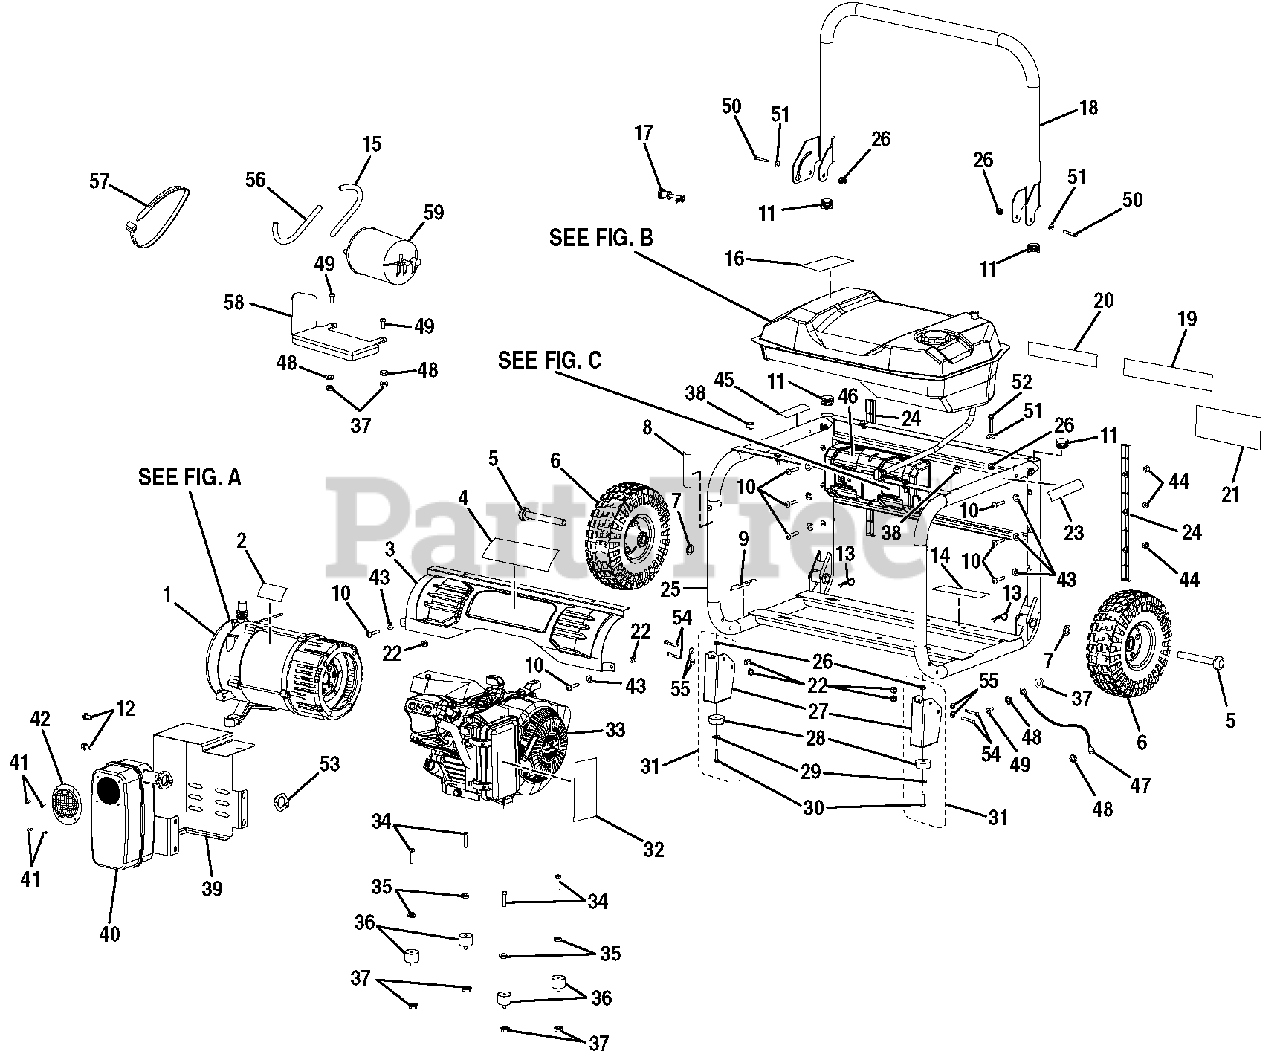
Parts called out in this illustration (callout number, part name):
1	Generator Head Assembly (See Figure A)
2	Data Label
3	Back Panel Assembly
4	Back Panel Logo Label
7	Washer (5/8 in.)
8	Hot Surface Label
9	Label (UL fire warning)
10	Bolt (1/4-20 x 42.5 mm, Torx Hd.)
12	Bolt (5/16-24 x 5/8 in.)
13	Hitch Pin
14	Lubricant Label
15	Purge Hose
16	CPSC Label
17	Handle Release Pin Assembly
18	Handle Assembly
19	Danger Label
20	Ground Warning Label
21	Logo Label
22	Lock Nut (1/4-20)
23	Fire Danger Label
24	Frame Slide Rails
25	Frame Assembly
26	Lock Nut (M8)
29	Washer (1/4 in.)
30	Bolt (1/4-20 x 1 in., Hex Hd.)
31	Foot Assembly
32	Starting Instruction Label
34	Bolt (5/16-18 x 1.5 in.)
35	Lock Washer (5/16)
36	Isolator (Generator)
37	Hex Nut (5/16-18, Flange Hd.)
38	Rubber Handle Bumper
39	Back Muffler Cover
40	Muffler (Subaru EX30)
41	Screw (8-32 x 3/8 in.)
42	Spark Arrestor
43	Lock Washer (M6)
44	Hex Nut (1/4-20)
45	Pin Release Label
46	Control Panel (See Figure C)
47	Ground Wire Assembly
48	Star Washer (5/16 in.)
49	Bolt (5/16-18 x 3/4 in.)
50	Bolt (M8 x 55 mm, Hex Hd.)
51	Washer (3/8 in.)
52	Bolt (1/4-20 x 1 in.)
53	Muffler Gasket
54	Bolt (1/4-20 x 2 in., T30 Torx Hd.)
55	Washer (1/4 in.)
56	Rollover Hose
57	Cable Tie (18.6 in.)
58	Bracket (Carb. Canister)
60	Danger Hang Tag
61	Combustion Label
